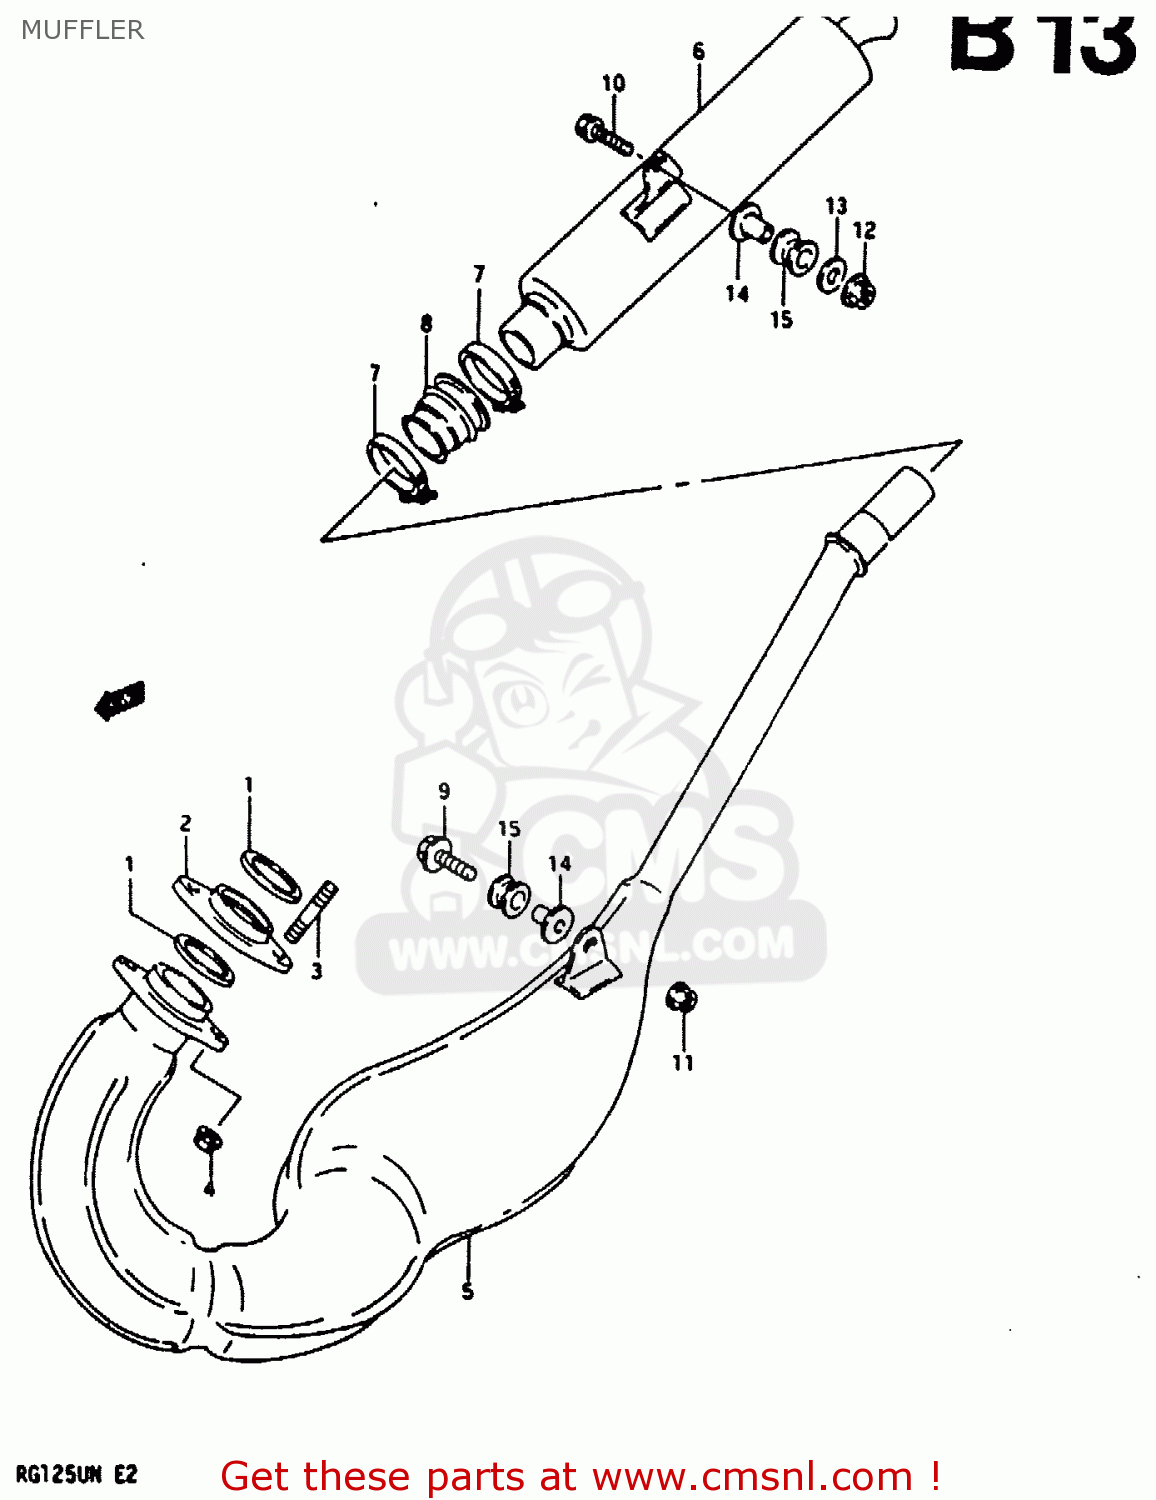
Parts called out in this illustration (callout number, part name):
1	GASKET,EXHAUST PIPE (NAS)
2	FLANGE,EXHAUST FITING
3	STUD BOLT
4	NUT
5	BODY, MUFFLER, 1ST
6	MUFFLER ASSY, 2ND
7	CLAMP
8	CONNECTOR,2ND MUFFLER
9	BOLT 8X35
10	BOLT
11	NUT 8MM
12	NUT
13	WASHER
14	SPACER(8.6X12X17.5)
15	CUSHION
